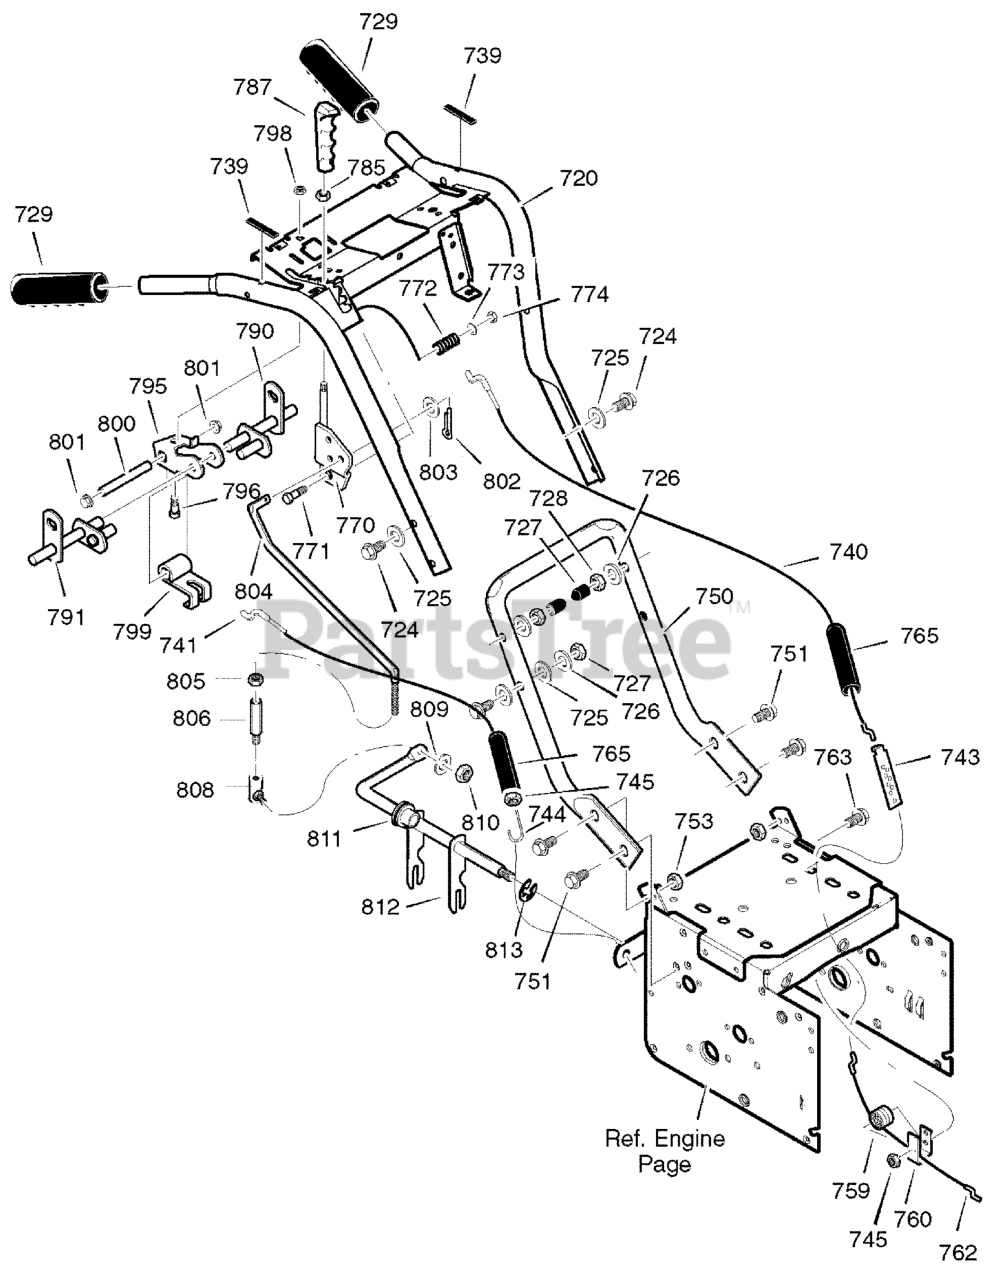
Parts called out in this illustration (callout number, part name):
720	ASSY, HANDLE
724	SCREW
725	WASHER, FLAT
726	WASHER
728	STOP, PLASTIC
729	GRIP, HANDLE
739	BUMPER
740	CABLE, CLUTCH
741	CABLE, CLUTCH
743	BRKT, CABLE ADJ
744	SPRING, CLUTCH
745	NUT, HEX
750	HANDLE, LOWER
751	SCREW
753	NUT, 5/16-18
759	SPOOL, CABLE
760	BRKT, SPOOL
762	CABLE, DRIVE
763	BOLT, HEX
765	BOOT, CABLE
770	BRACKET, SHIFT
771	SCREW
772	SPRING
773	WASHER, FLAT
774	NUT, HEX
785	NUT, HEX
787	KNOB, SHIFT
790	ROD, ASSY LH
791	ROD, ASSY RH
795	BRACKET, CAM
796	SCREW
798	NUT, NYLOCK
799	CAM LOCK
800	PIN, SPRING PIVOT
801	NUT, PUSH ON
802	PIN, COTTER
803	FLATWASHER
804	ROD, SPEED CTRL
805	NUT, 5/16-18
806	ADAPTER, ROD
808	BALLJOINT, STEEL
809	WASHER
810	NUT, 5/16-18
811	BEARING, FL
812	ROD, YOKE
813	RETAINER, RING
